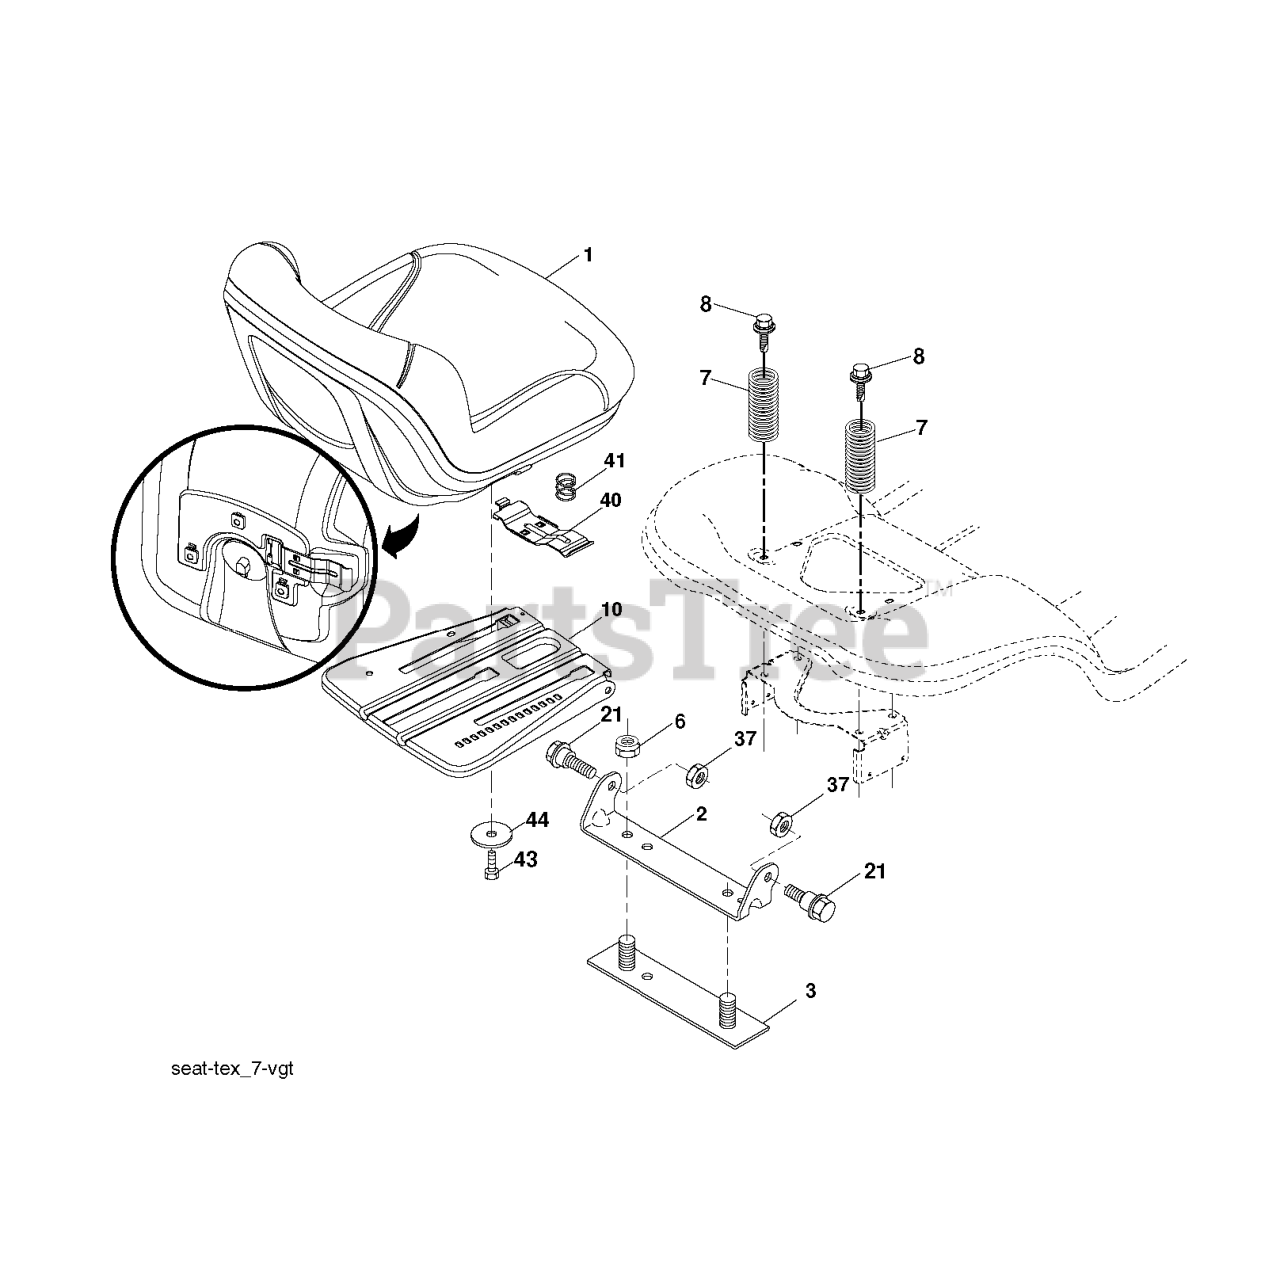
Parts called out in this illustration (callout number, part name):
1	SEAT - GREY
2	BRKT.PIVOT.FENDER
3	STRAP
6	NUT
7	SPRING COMPRESSION
8	BOLT.5/16-18UNCX3/4 W/SEMS.BLK
10	PAN.ASM.SEAT.3PT
21	BOLT.SHOULDER.5/16-18
37	NUT.71038.31-18.HEX.NYLOCK
40	HANDLE.SLIDE.SEAT.TEX.BLACK
41	SPRING.LATCH.SEAT.TEX
44	WASHER 13/32 X 2-3/8 X 12GA
